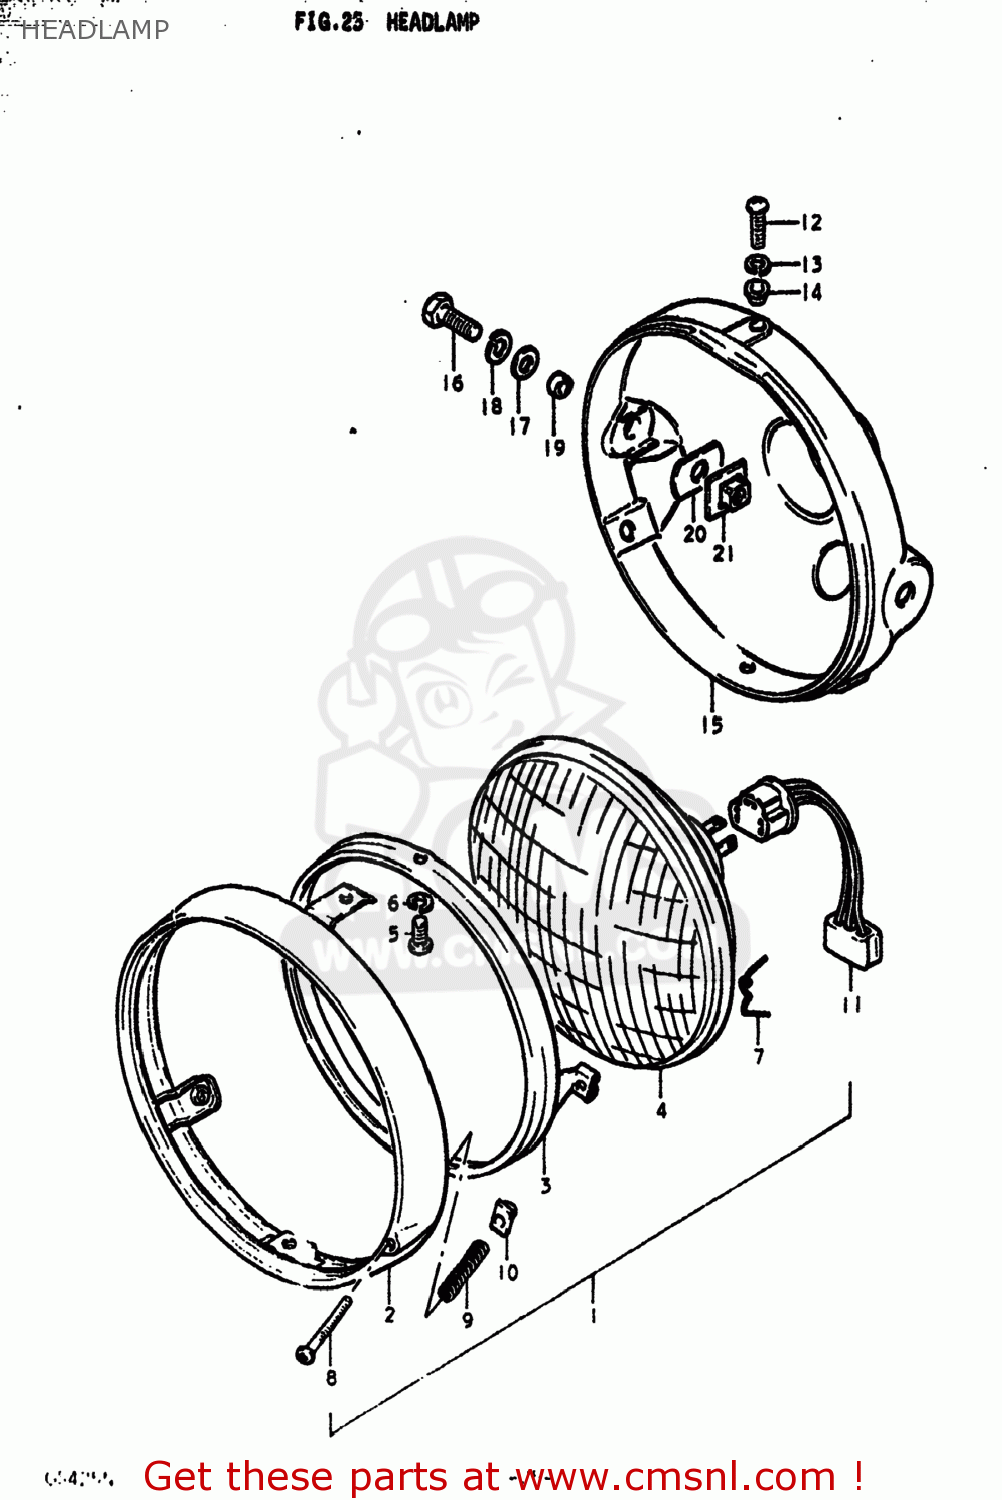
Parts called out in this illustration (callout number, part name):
1	HEADLAMP ASSEMBLY
2	RIM,HEADLAMP
3	RETAINER,HEADLAMP
4	LAMP UNIT
5	SCREW
6	LOCK WASHER
7	SPRING
8	SCREW,HEADLAMP ADJUST
9	SPRING
10	NUT
11	LEAD WIRE,HEADLAMP
12	SCREW
13	WASHER,LOCK
14	WASHER
15	HOUSING,HEADLAMP(BLACK)
16	BOLT
17	WASHER
18	LOCK WASHER
19	SPACER (8.8X12X7)
20	CUSHION
21	PLATE,HEADLAMP HOUSING
